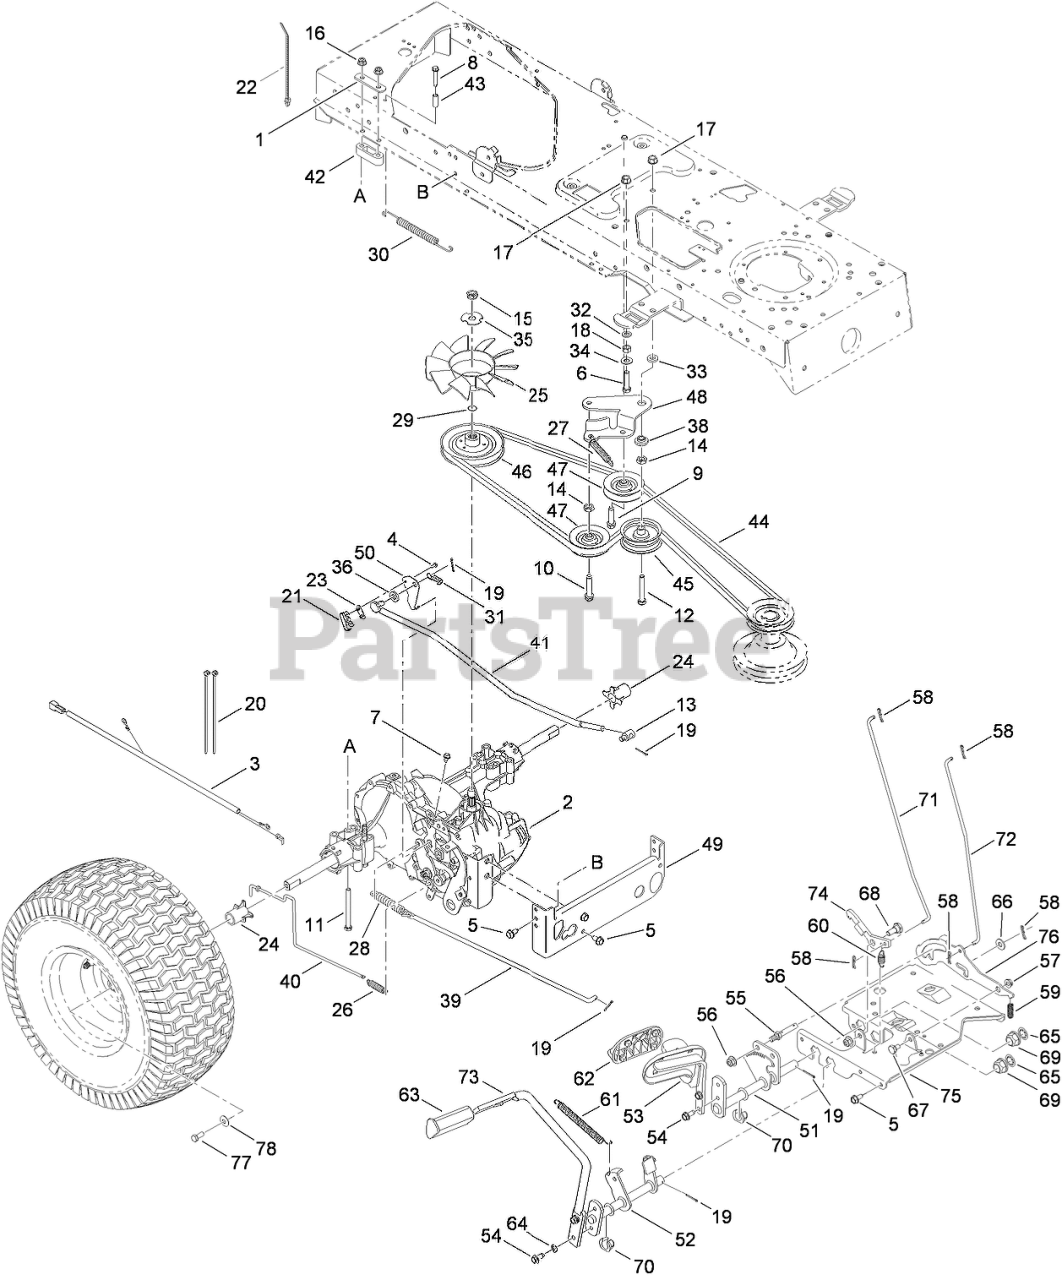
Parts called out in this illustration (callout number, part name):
1	BRACKET-MOUNTING, TRANSMISSION
2	HYDRO TRANSMISSION ASM
3	BRACKET-PIVOT, SUPPORT
4	FAN-BLADE, 10
5	SCREW-TAP
6	SCREW-HH
7	SCREW-TAP
8	SCREW-HWH
9	SCREW-TAP
10	SCREW-TAP
11	SCREW-HH
12	SCREW-HH
13	FERRULE
14	NUT-JAM
15	NUT-JAM
16	NUT-LOCK, FLANGE
17	NUT-LOCK, FLANGE
18	NUT-LOCK, FLANGE
19	PIN-COTTER
20	TIE-CABLE
21	SWITCH-SPRING, SHORT
22	TIE-CABLE
23	PLATE-INSULATOR
24	SLEEVE
26	SPRING-EXTENSION
27	SPRING-EXTENSION
28	SPRING-EXTENSION
29	RING-WIRE
30	SPRING-EXTENSION
31	SPRING-EXTENSION
32	WASHER-LOCK
33	WASHER-FLAT
34	WASHER-FLAT
35	WASHER-LOCK
36	WASHER-FLAT
38	SPACER-SHOULDER
39	ROD-BRAKE
40	ROD-HYDRO
41	ROD-CONTROL
42	SPACER-TRANSAXLE
43	SPACER
44	BELT-V
45	PULLEY-IDLER, FLAT
46	PULLEY-INPUT
47	PULLEY-IDLER, Y TYPE
48	BRACKET-IDLER, CENTER DOUBLE
49	BRACKET-TORQ, TRANSMISSION
50	BRACKET-ACTUATOR
51	CONTROL ASM
52	SPEED CONTROL ASM
53	CONTROL PEDAL ASM
54	SCREW-HWH
56	NUT-LOCK, FLANGE
57	NUT-LOCK, FLANGE
58	PIN-COTTER
59	SPRING
60	SPRING-EXTENSION
61	SPRING-EXTENSION
62	PAD-PEDAL
63	PAD-BRAKE
64	WASHER-LOCK
65	WASHER-FLAT
66	Washer-Flat
67	BOLT-SHOULDER
68	BOLT-SHOULDER
69	BEARING-FLANGE
70	BEARING-FLANGE, HEX (SPLIT)
71	ROD-BRAKE, LOCK
72	ROD-CONTROL, CRUISE
73	PEDAL-BRAKE
74	LATCH-CRUISE
75	BRACKET-SUPPORT, STEERING
76	BRACKET-LOCKOUT
77	SCREW-HH
78	WASHER-BELL
